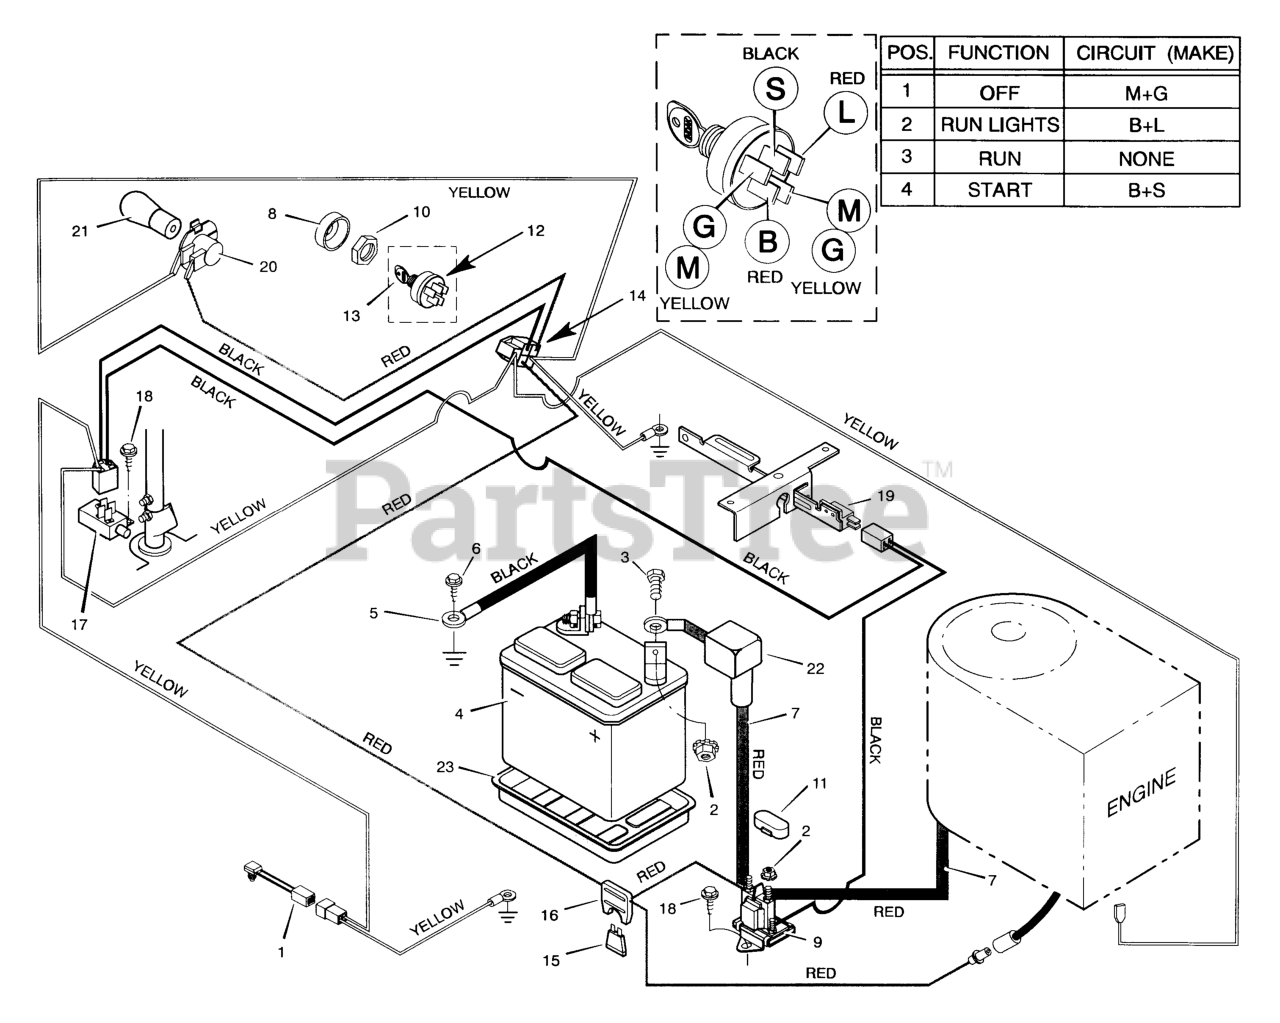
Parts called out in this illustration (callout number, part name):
1	Switch, Seat Sensor
2	Locknut
4	Battery
5	Cable, Battery Ground
7	Cable, Red Battery
8	Cap, Ignition
9	Solenoid
10	Nut, Hex
11	Cover, Solenoid
12	Switch, Ignition
13	Key, Ignition
14	Harness, Chassis Wire
16	Holder, Fuse
17	Switch, Limit
19	Switch, Limit
20	Socket, Light
21	Bulb, Light
22	Cover, Terminal
23	Tray, Battery
